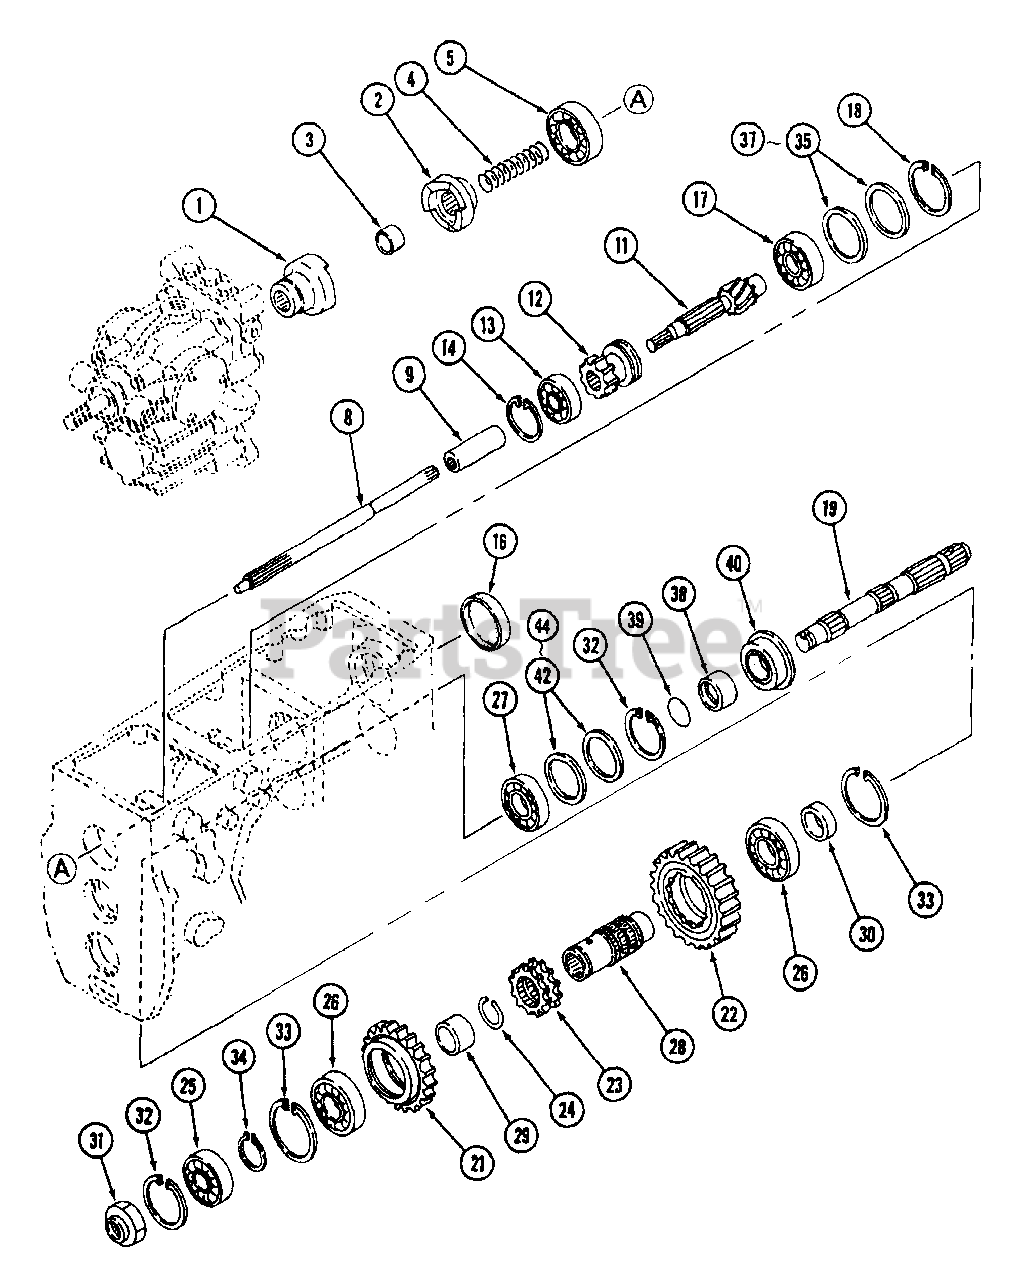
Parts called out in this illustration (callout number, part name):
1	Clutch A
4	Spring
9	Collar
11	Shaft, PTO Drive
12	Gear, 19T
34	Ring
35	Liner
36	Liner
37	Liner
40	Seal, Oil
42	Liner
43	Liner
44	Liner
